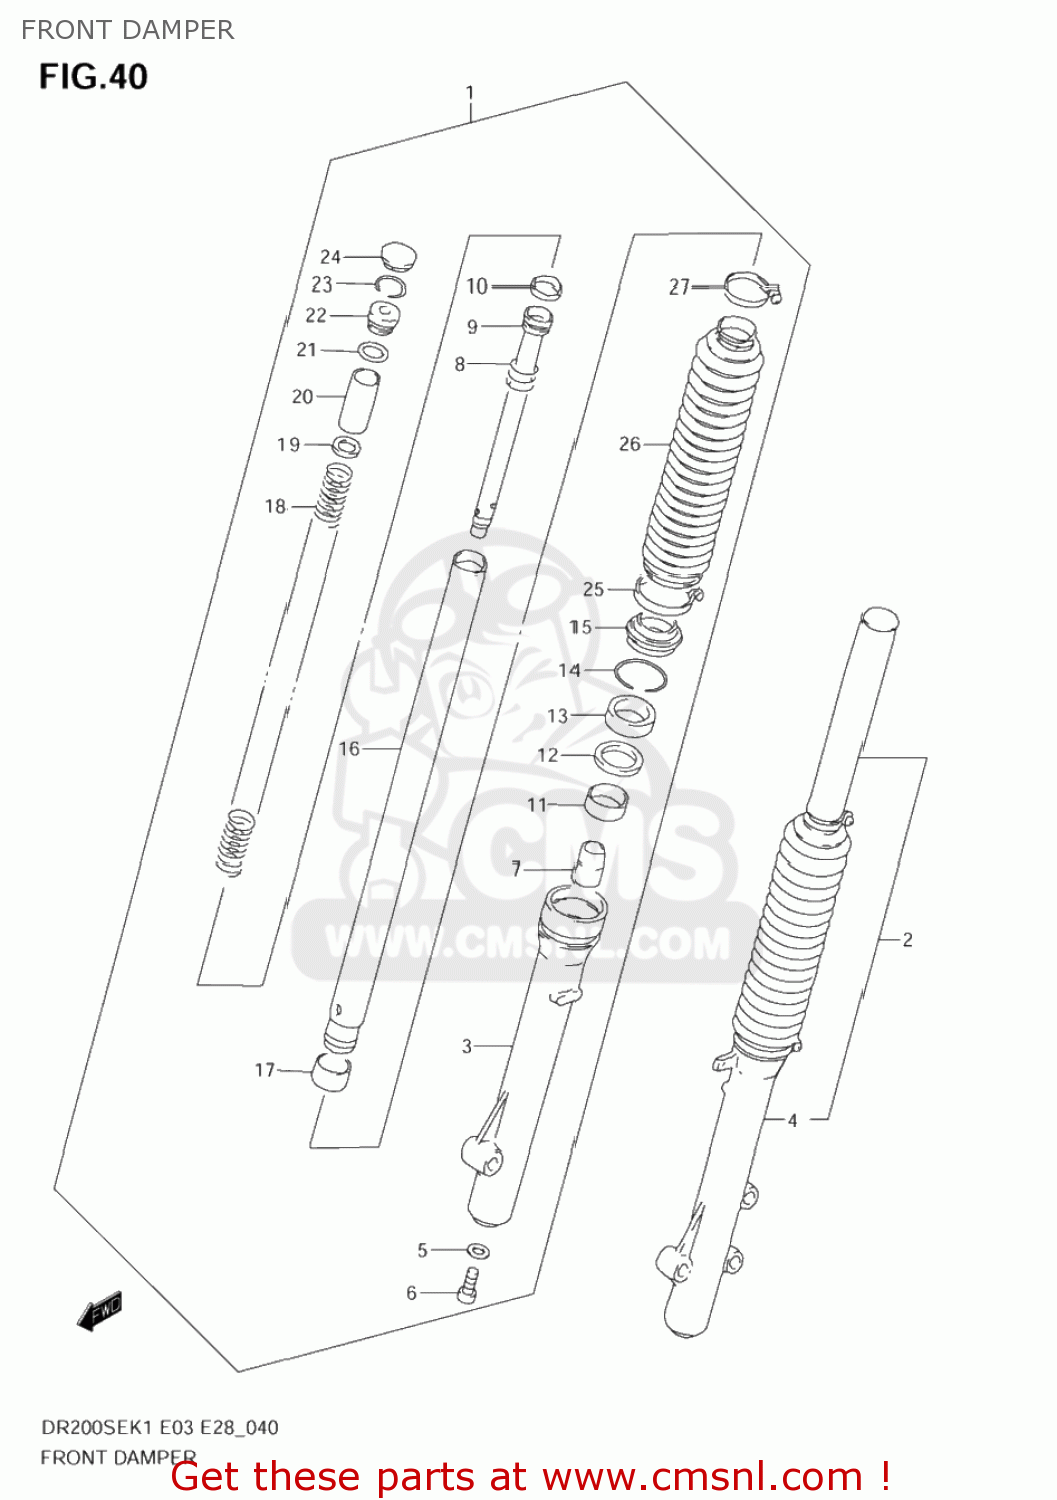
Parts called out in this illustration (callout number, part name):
1	DAMPER ASSY,FR FORK,R
2	DAMPER ASSY,FR FORK,L
3	TUBE,OUTER,R
4	TUBE,OUTER,L
5	GASKET (NAS)
6	BOLT,CENTER (8X18)
7	PIECE,OIL LOCK
8	SPRING,REBOUND
9	CYLINDER
10	RING,PISTON
11	BUSH,GUIDE
12	SPACER,SEAL
13	SEAL,OIL 35X48X11
14	RING,OIL SEAL STOPPER
15	SEAL,DUST
16	TUBE,INNER
17	PISTON
18	SPRING,MAIN
19	SPRING,JOINT
20	SPACER,SPRING
21	O RING
22	SPRING SEAT B
23	RING,STOPPER
24	CAP
25	BAND,BOOT LWR
26	BOOT
27	BAND
